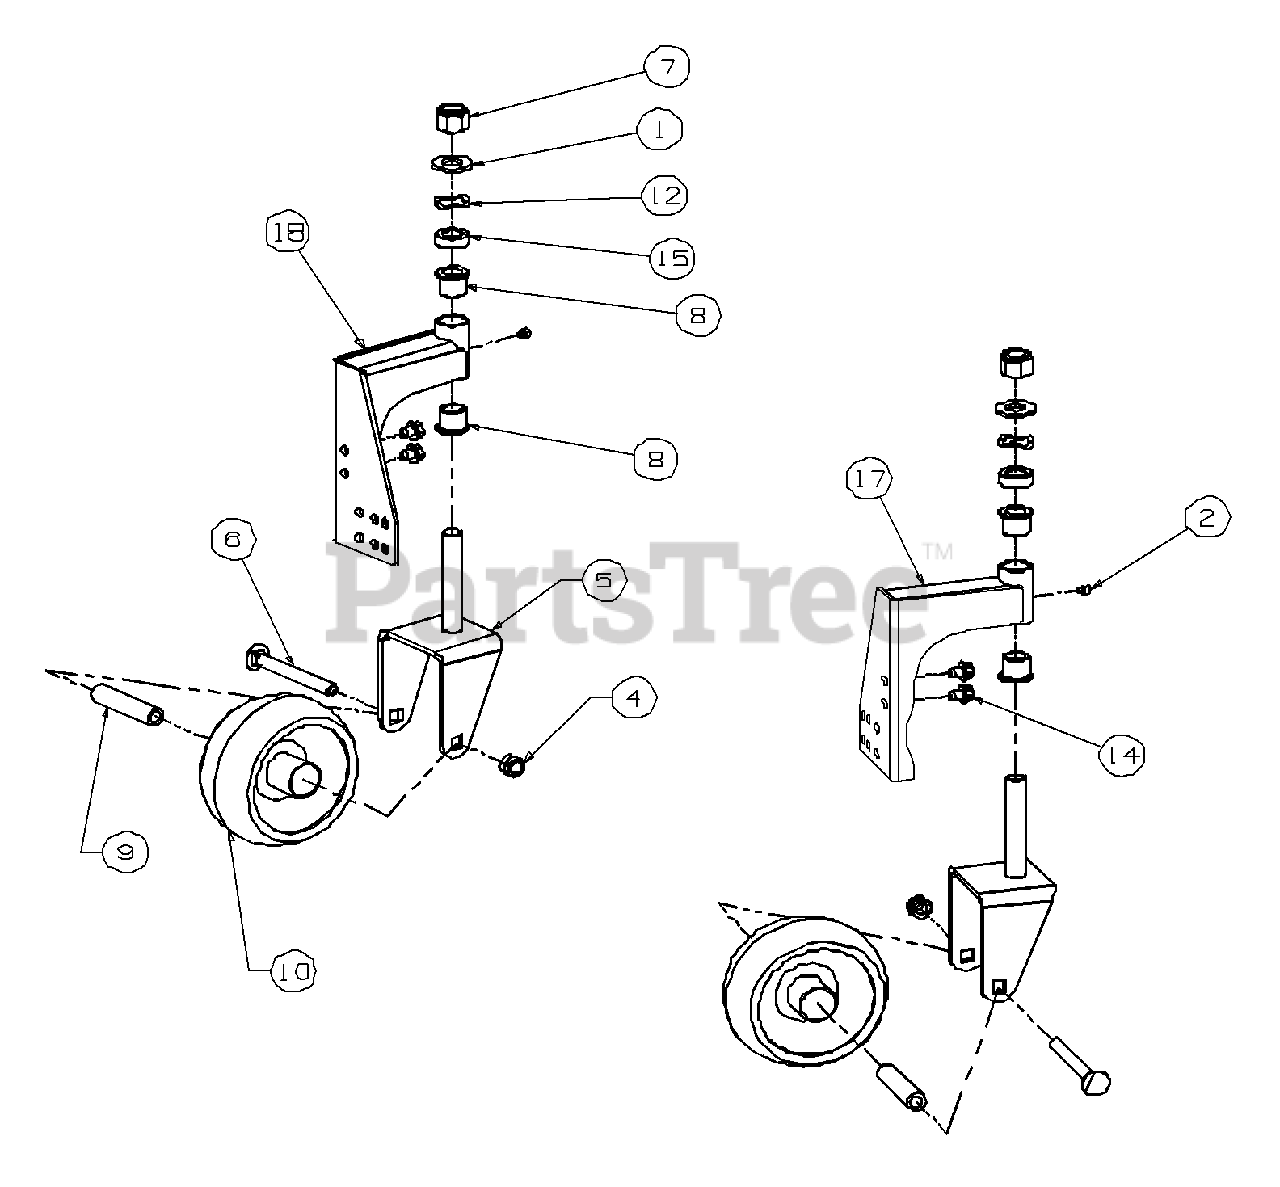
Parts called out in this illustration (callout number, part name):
1	WASH:FL:.750 X 1.50 X .120 THK
2	FTG:GRS:1/4-28 X 3/16 STR
4	NUT:HX:1/2-13:GR5
5	YOKE ASM:CSTR WHL
6	SCR:CARR:1/2-13 X 4.50:GR5
7	NUT:HX:3/4-10:GR5:LOCK
8	BRG:FLG:.754 ID X 1.00 OD X .925
9	AXLE:CSTR WHL
10	WHL ASM:6.25 X 3.00-4:WHITE
12	WASH:WAVE:1.38 OD X .88 ID X .02
14	SCR:TT:3/8-16 X .500:HXINDWSH
15	SPCR:.76 ID X 1.25 OD X .44 LG
17	ASM:LH DECK CSTR BRKT
18	ASM:RH DECK CSTR BRKT
